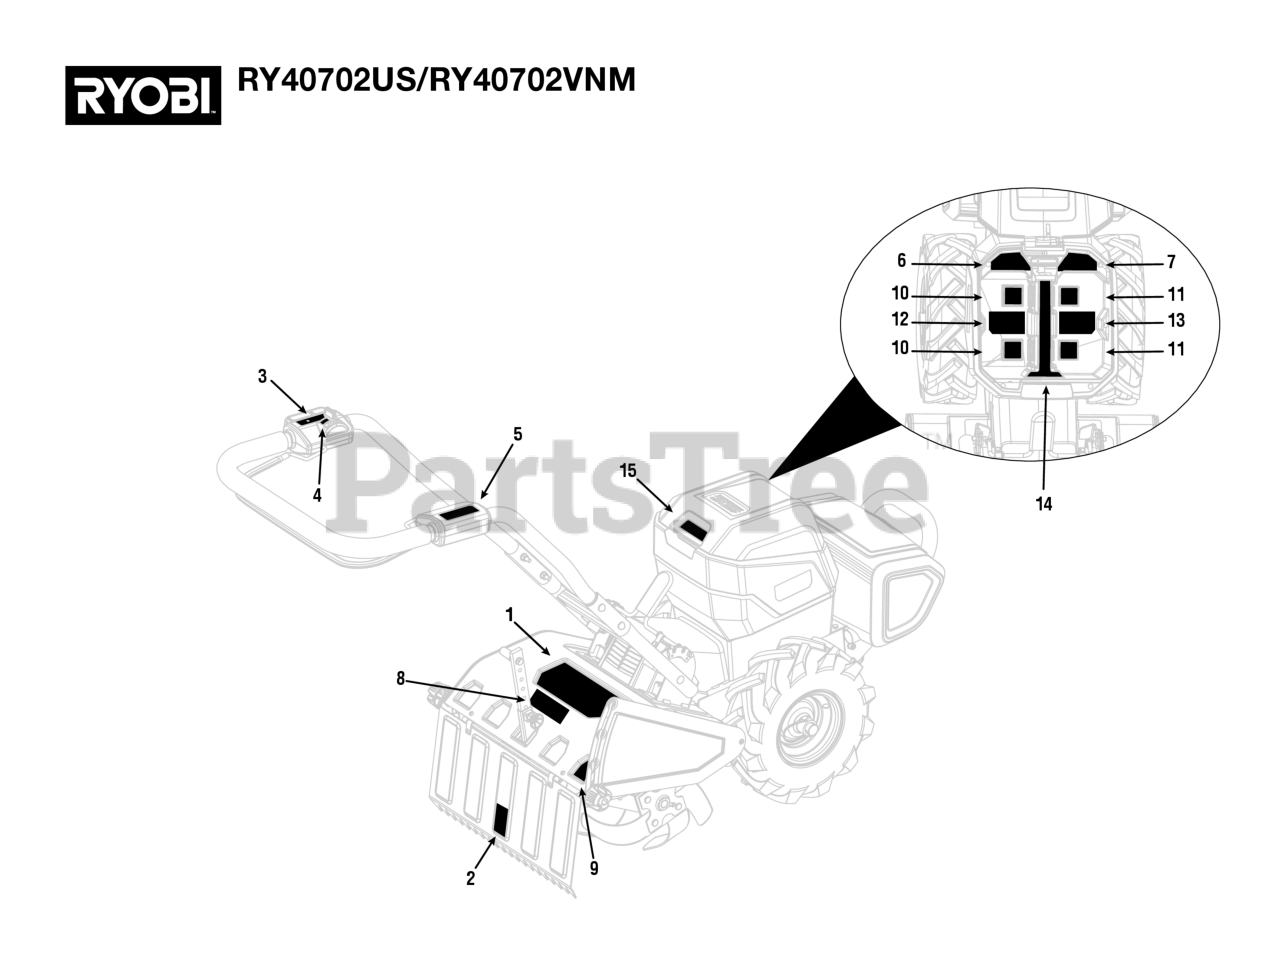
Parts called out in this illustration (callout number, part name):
1	Data/Icon/Warning Label
2	Cut Foot/Hands Label
3	LED Indicators Label
4	Wheel Speed Label
5	Starting Instructions Label
6	Pair A Top Label
7	Pair B Top Label
8	Depth Stake Label
9	Side Panel Instruction Label
12	A Min Battery Label
13	B Min Battery Label
14	Center Label
15	Tilling Width Label
